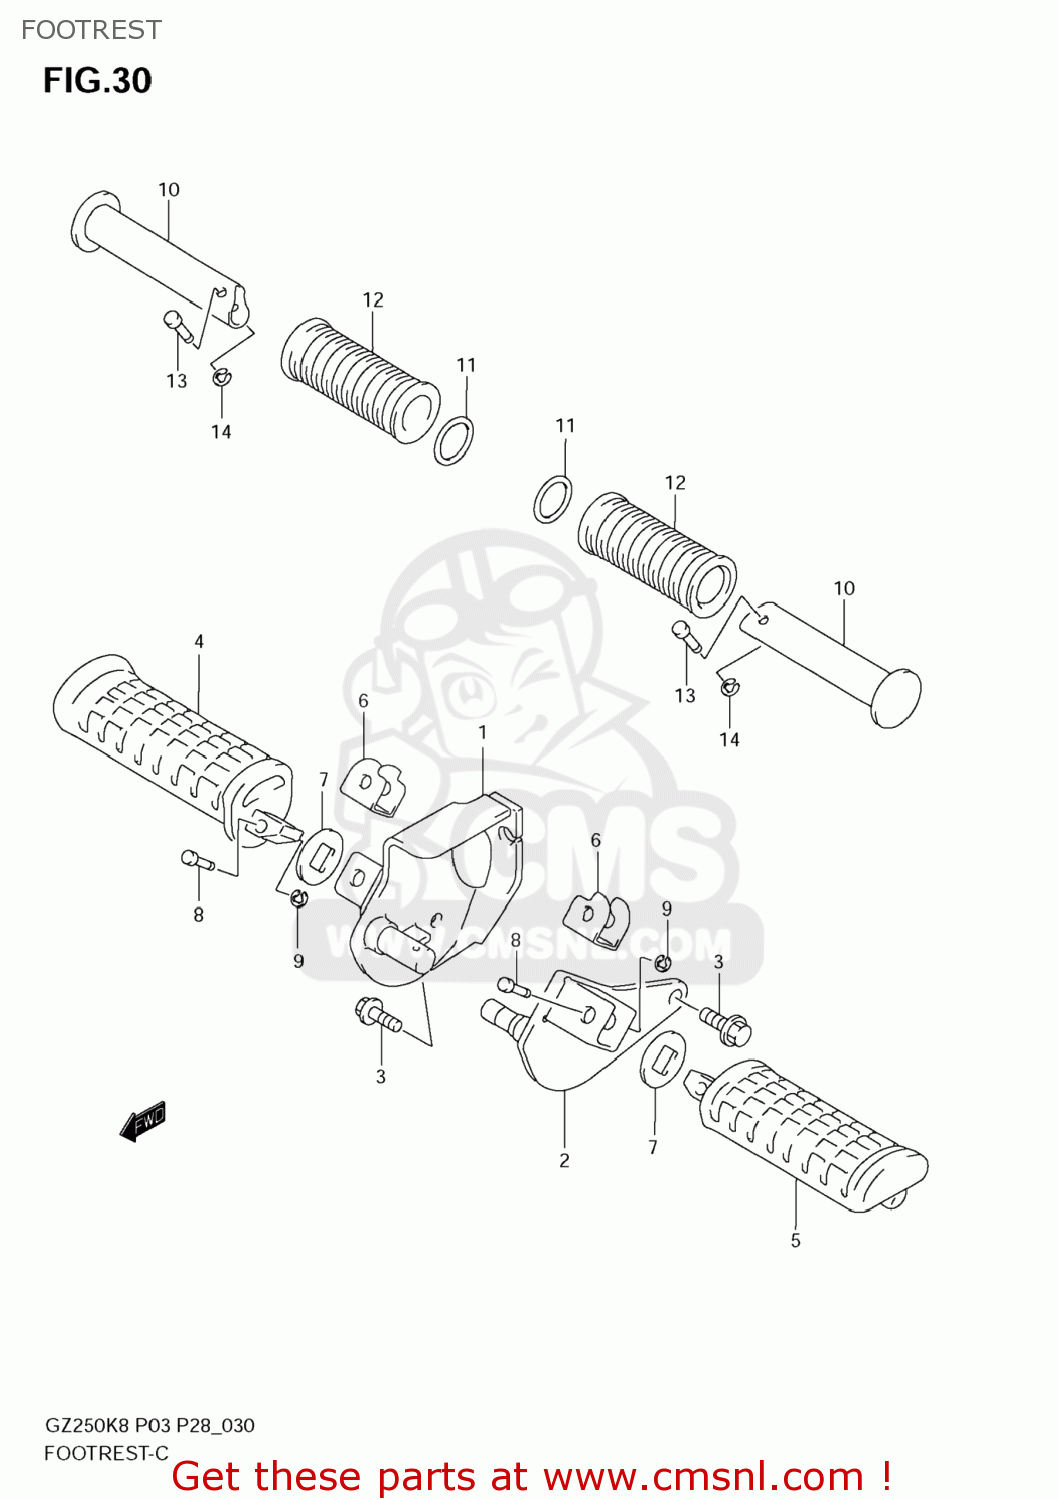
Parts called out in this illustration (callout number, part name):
1	BRACKET COMP.
2	BRACKET COMP.
3	BOLT
4	RUBBER, FRONT FOOTREST RH
5	RUBBER, FRONT FOOTREST LH
6	CUSHION,FR FOOTREST
7	WASHER,FOOTREST RUBBER
8	PIN(6X29.5)
9	E RING
10	BAR,FOOTREST RUBBER
11	WASHER(19.5X32X2)
12	RUBBER PILLION
13	PIN,PILLION FOOTREST
14	E RING
